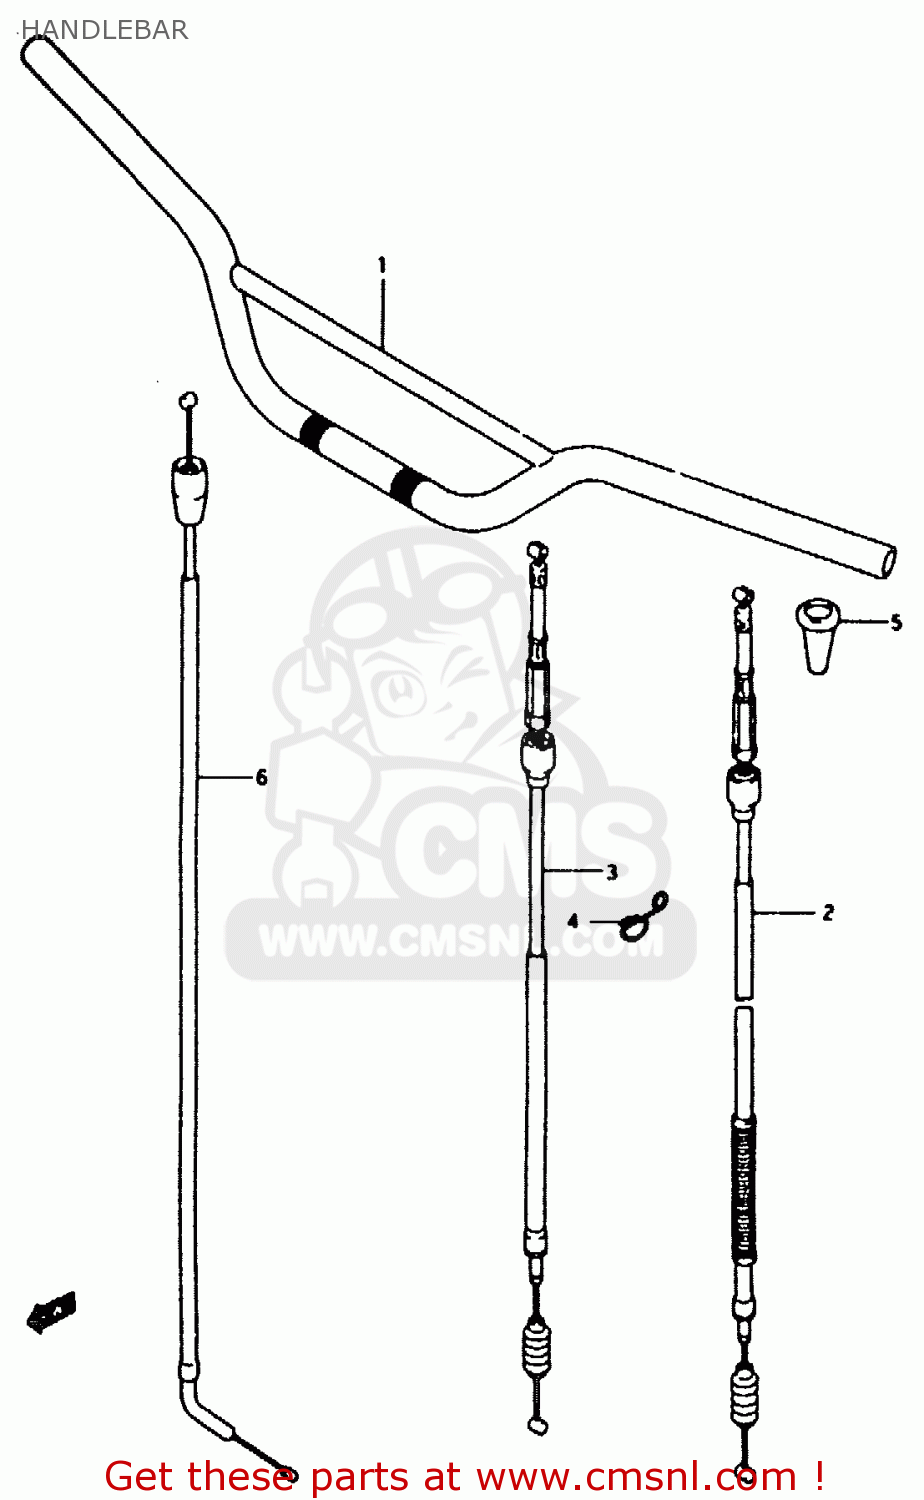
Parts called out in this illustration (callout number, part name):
1	HANDLEBAR
2	CABLE ASSY,CLUTCH
3	CABLE ASSEMBLY,CLUTCH
4	CLAMP,CLUTCH CABLE NO
5	BOOT,CLUTCH CABLE
6	CABLE ASSY,THROTTLE
